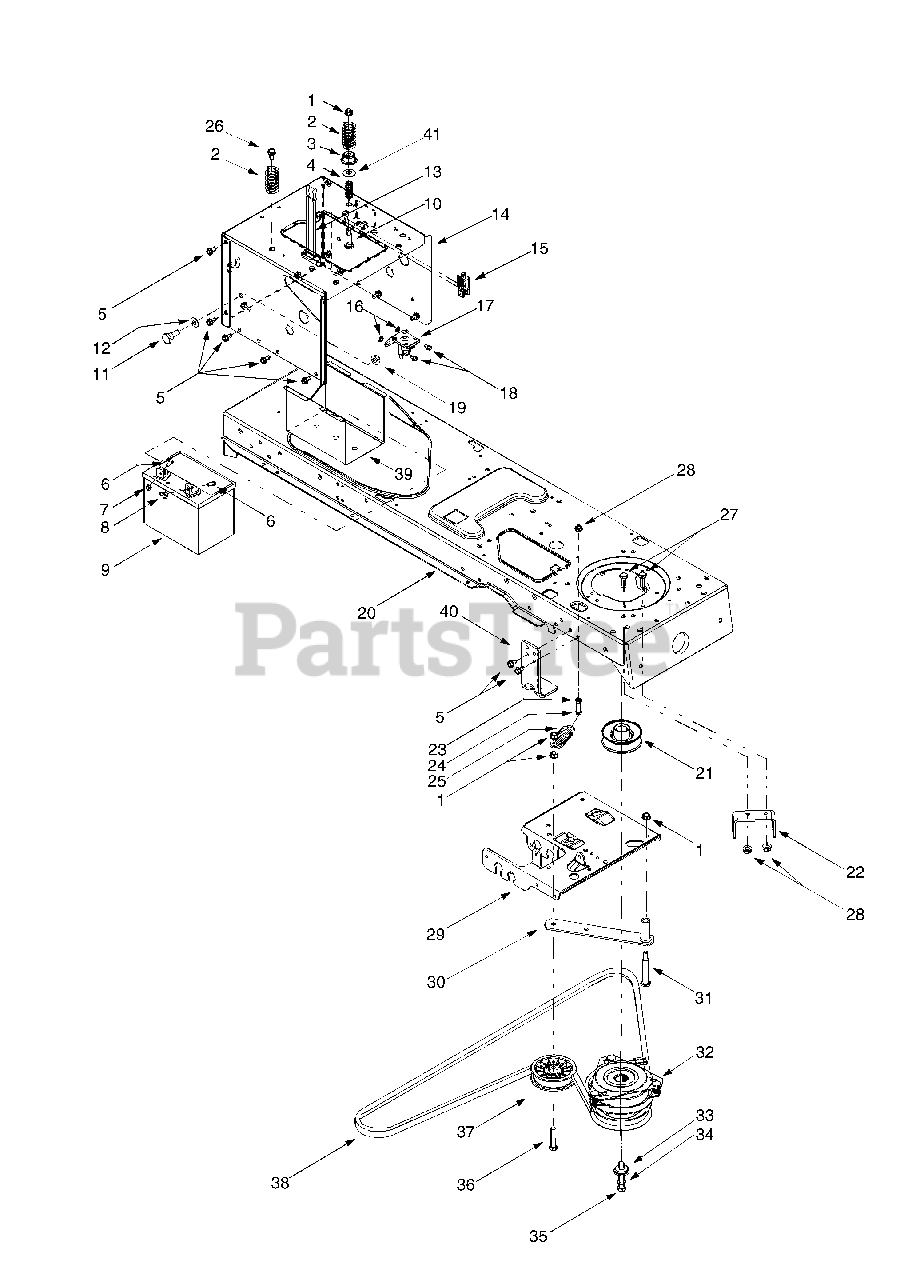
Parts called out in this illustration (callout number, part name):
1	Flange Lock Nut, 3/8-16
2	Compression Spring, 1.318 x 2.37
3	Spacer Cup, 1.5 OD
4	Compression Spring, .66 OD x 1.5
5	Self Tapping Screw, 5/16-18 x .625
6	Hex Cap Screw, 1/4-20 x .62
7	Hex Sems Nut, 1/4-20
8	Wing Nut, 1/4-20
9	12-volt Battery, 270 CCA
10	Shoulder Screw, .5 x 1.25, 3/8-16
11	Shoulder Screw, .625 x .5, 7/16-20
12	Bell Washer, .45 x 1.0 x .062
13	Battery Strap
16	Lock Washer, 1/4
17	Solenoid, 12-Volt, 100 Amp
18	Self Tapping Screw, 1/4-20 x .5
19	Flange Lock Nut, 7/16-20
24	Hex Cap Screw, 5/16-18 x 1.75 (Grade 5)
25	Extension Spring, 1.2 OD x 3.638
26	Self-tapping Screw, 5/16-18 x .875
27	Hex Cap Screw, 5/16-18 x .625
28	Flange Lock Nut, 5/16-18
29	Steering Support Bracket
32	Electric PTO Clutch
33	Shoulder Spacer, 1.38 x .445 x .36
34	Lock Washer, 7/16
35	Hex Cap Screw, 7/16-20 x 3.25 (Grade 5)
36	Hex Cap Screw, 3/8-16 x 2.25 (Grade 5)
37	Flat Idler Pulley, 3.5 OD
38	PTO Belt
